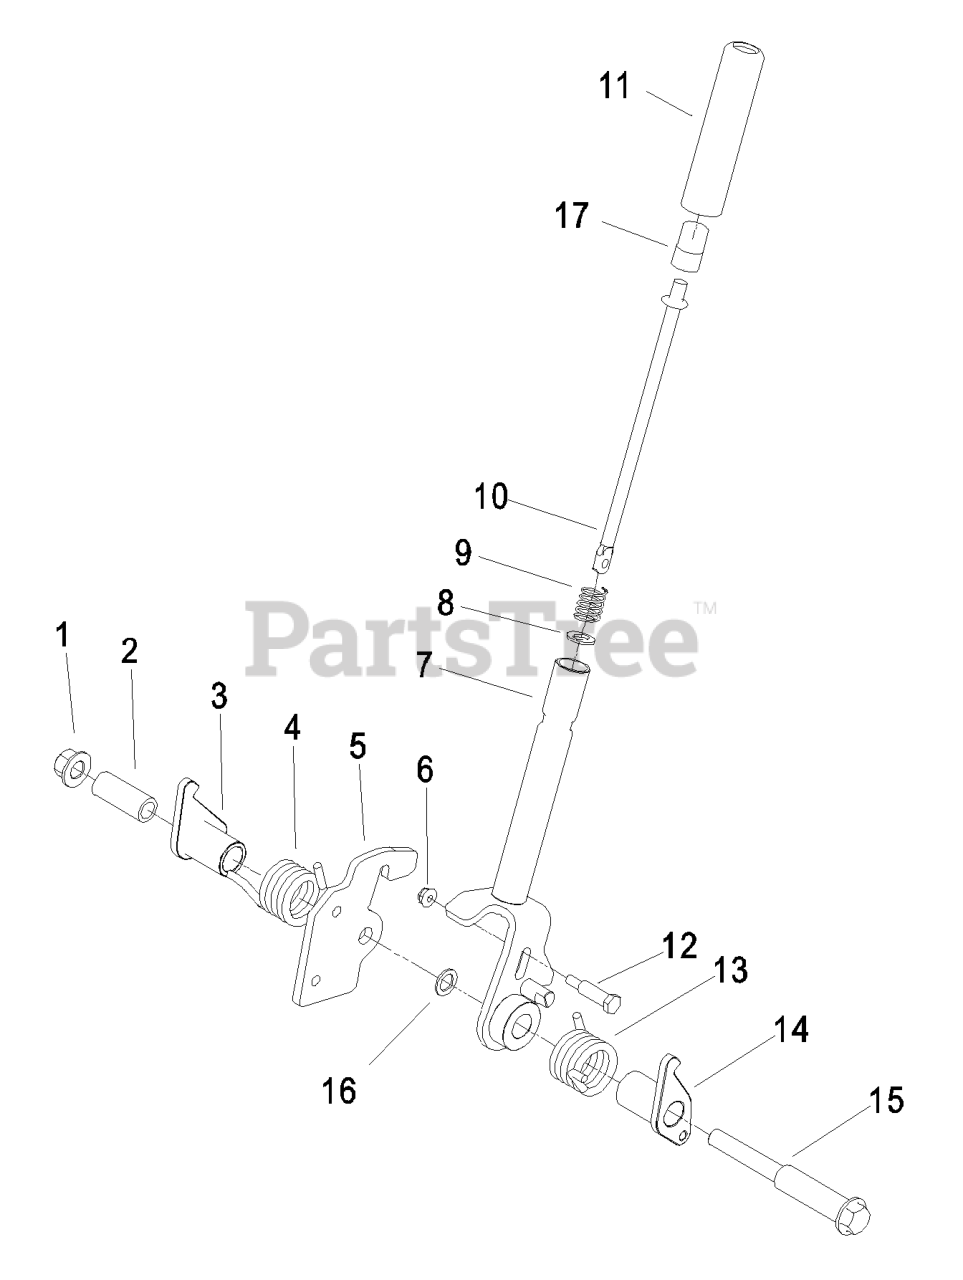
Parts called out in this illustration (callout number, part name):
1	Nut-Lock 1/2-13
3	ARM-BRAKE, LH
4	SPRING-TORSION, RH
5	PLATE-LATCH
8	WASHER-SPECIAL
9	SPRING-COMPRESSION
10	ROD-RELEASE, BRAKE
12	BOLT-SHOULDER
13	SPRING-TORSION, LH
14	ARM-BRAKE, RH
15	BOLT-SHOULDER
